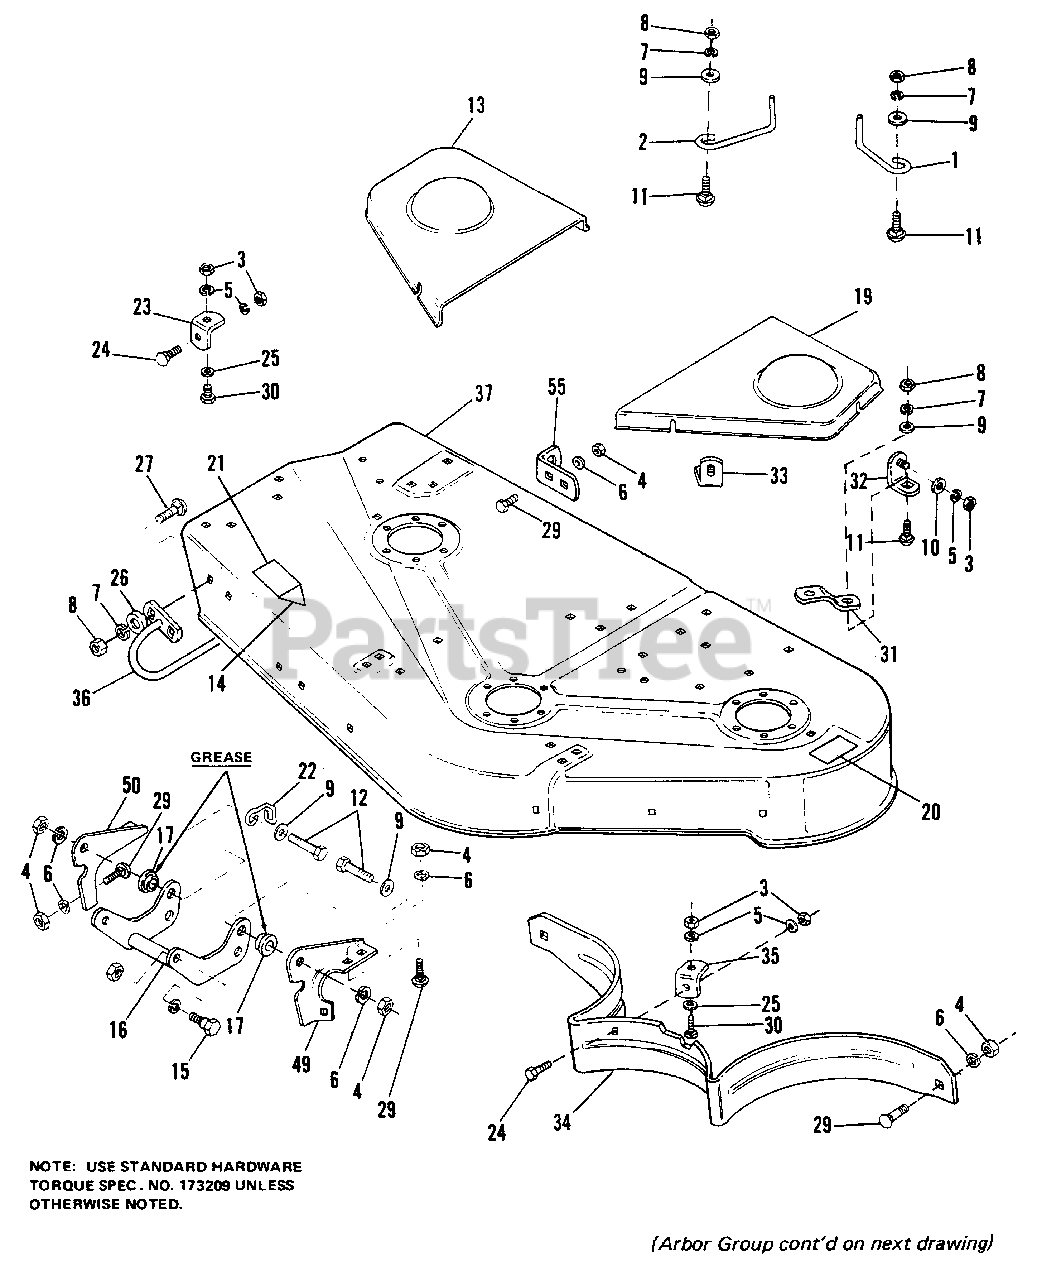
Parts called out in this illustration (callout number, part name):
2	Stop Belt
3	NUT Hex, 1/4-20
4	NUT Hex, 3/8-16
5	LOCKWASHER, Spring, 1/4
6	LOCKWASHER, Spring, 3/8
7	LOCKWASHER, Spring, 5/16
8	NUT, Hex, 5/l6-18
9	WASHER, Plain, 5/16
10	WASHER, Plain, 1/4
11	BOLT, Carriage, 5/16-18 x 3/4
12	CAPSCREW, Hex Hd., 3/8-16 x 1-1/2
13	COVER, R.H. Arbor
14	DECAL, OPEI
15	BOLT, Shoulder
16	ARM ASSY, Mower Front
19	COVER, L.H. Arbor
20	DECAL, Danger
21	DECAL, Warning
22	GUIDE, Cable
23	CLIP, Baffle
24	BOLT, Carriage, 1/4-20
25	WASHER, Plain, 1/4
26	WASHER, Plain, 5/16
27	BOLT, Carriage. 5/16-16
29	BOLT, Carriage, 3/8-16 x 3/4
30	CAPSCREW, Hex Hd., 1/4-20
31	CLIP, Spring
32	LEG ASSY, Arbor Cover.
33	LEG ASSY, Arbor Cover
34	BAFFLE, Center, 42"
35	CLIP
37	HOUSING, 42" Mower
49	BRACKET, L.H. Front
50	BRACKET, R.H. Front
55	BRACKET, Roller Support
